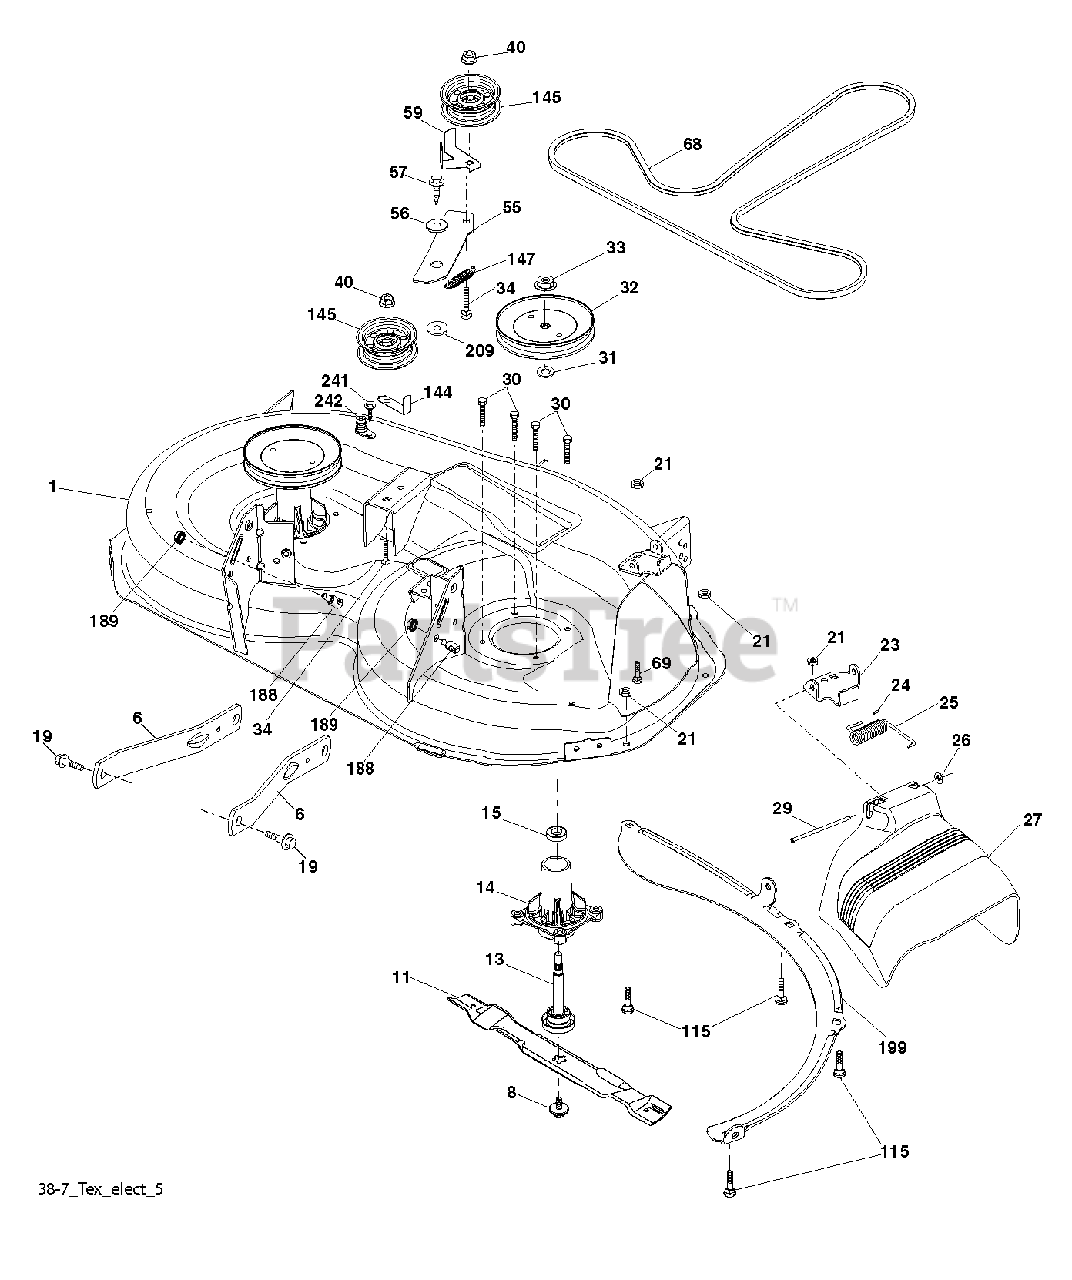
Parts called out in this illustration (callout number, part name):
1	DECK.WELD.38.NGW.TX.W/HOL.GREY
6	ARM.SUSPENSION.MOWER.R
8	BOLT.WASHER.ASM.7/16-2
11	BLADE.HI.LIFT.38"
13	SHAFT.ASM.MDRL.N/GREASE.38
14	HOUSING.MANDREL.4PT.
19	BOLT.SHOULDER
21	LOCKNUT
23	BRKT.DEFLECTOR.38"2005+
24	CAP-SLEEVE LT
25	SPRING.TORSION.DEFLECT
26	NUT PUSH M
27	SHIELD.DEFLECTOR.MWR.38-7/97CM
29	ROD.HINGE
30	SCREW, WASHER HEAD
31	WASHER.SPACER.MANDREL
32	PULLEY MANDREL
33	NUT.FLANGE.LOCK.TOP
34	BOLT.3/8-16X1.50
40	NUT LOCK FLG 3/8-16 UNC
56	SPACER.RETAINER
57	SCREW 3/8-16X1
59	GUARD, BELT
69	BOLT
115	BOLT
144	KEEPER BELT
145	PULLEY.IDLER.48"PRIMARY
147	SPRING RETURN
188	STUD.FASTNER.W/ANTI-ROTATE
189	NUT LOCK HEX FLANGE 5/16-18
199	BAFFLE.VORTEX.FRONT.38"
209	WASHER 12/32X2X10GA
241	SCREW.TT.#10-32X.5.3/8.FLANGE
242	PORT.WASHOUT
